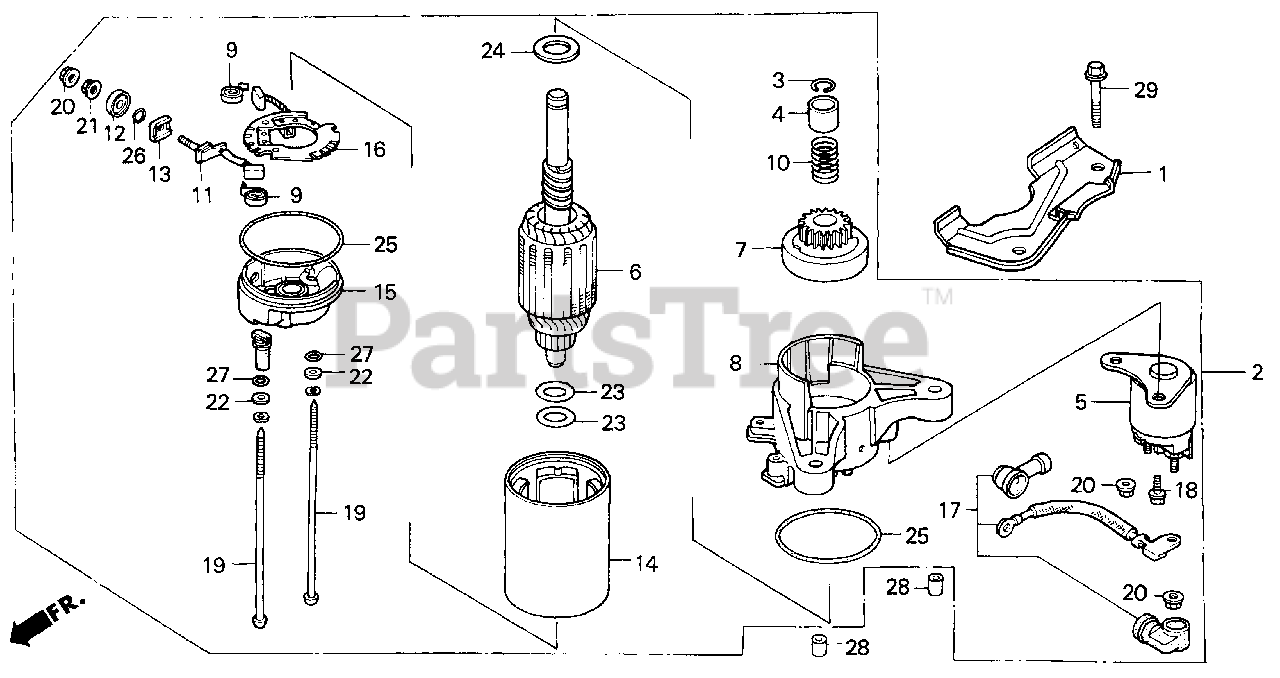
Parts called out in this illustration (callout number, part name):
1	PLATE, SIDE
2	MOTOR ASSY., STARTER
3	RING, SNAP
4	COLLAR, CLUTCH
5	CONTACTOR ASSY.
7	CLUTCH, OVERRUNNING
8	HOUSING, DRIVE SIDE
9	SPRING, BRUSH
12	BUSHING, INSULATION
13	BUSHING, INSULATION
15	FRAME, STARTER END
16	PLATE, BRUSH HOLDER
17	WIRE, WATER COVER
18	BOLT
19	BOLT, THROUGH (NOT AVAILABLE)
19	BOLT, THROUGH
22	WASHER, STEEL PLATE
23	WASHER
25	O-RING
27	O-RING
28	PIN A, DOWEL (10X16)
29	BOLT, FLANGE (8X35)
